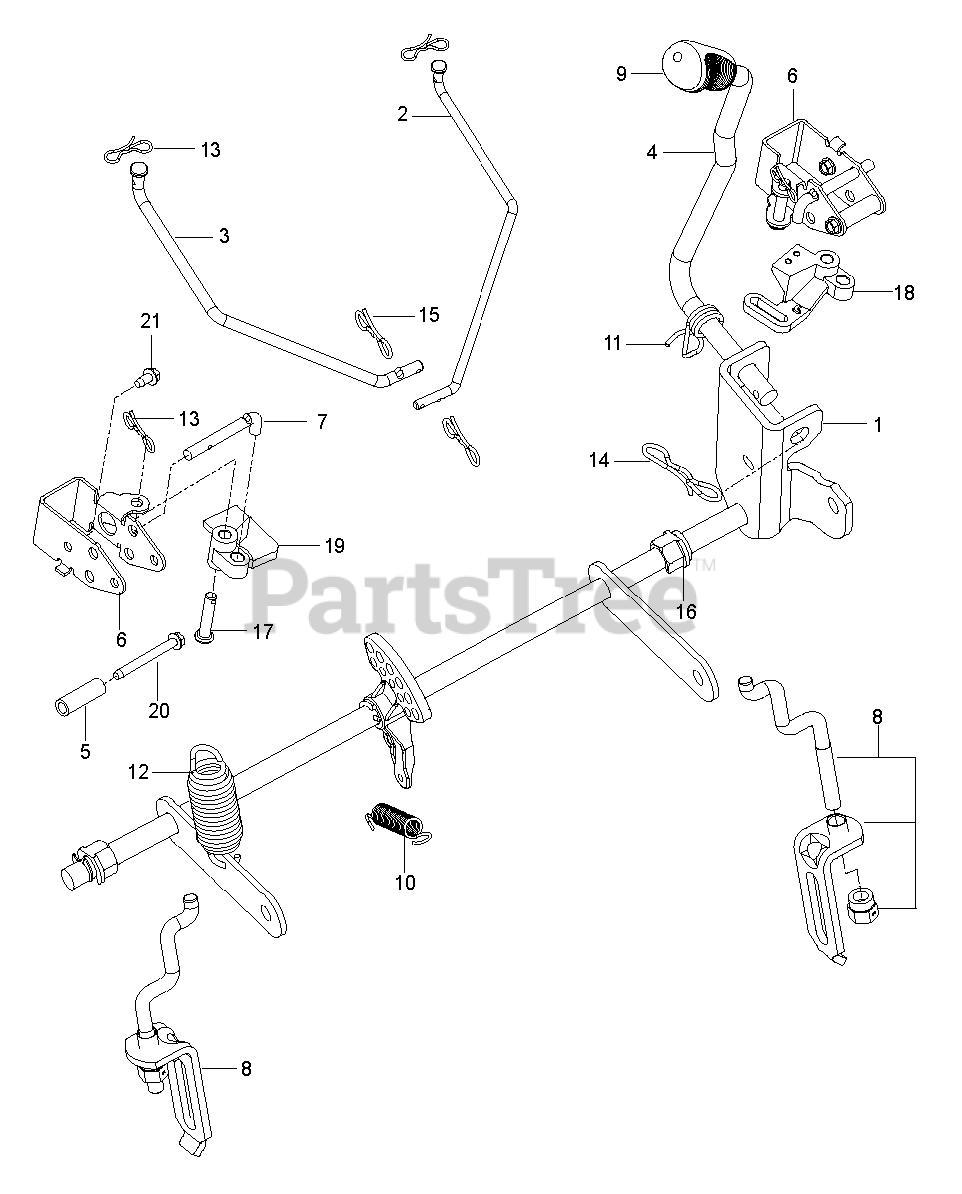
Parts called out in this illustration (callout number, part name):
1	SHAFT.ASM.RZ.DECK.LIFT.SRV
2	LINK.BRAKE.PARK.UPPER.LH
3	LINK.BRAKE.PARK.UPPER.RH
4	LIFT.LEVER.ASM.RZ.SERVICE
5	SPACER.334.ID.5.OD.1.5.L
6	BRACKET.BELLCRANK.PBRAKE X431
7	ROD.PUSH.BRAKE
8	LINK.ASM.RZ.LIFT.SERVICE
9	GRIP.HANDLE.LIFT.PVC.428
10	RETURN.BRAKE.PARK.AUTO
11	SPRING.TORSION.LIFT.HANDLE
12	SPRING
13	PIN COTTER;LOCKING;BOWTIE;1IN
14	SPRING.TORSION.LIFT.HANDLE
15	PIN.COTTER.5/16.BOW TI
16	PLASTIC NUT
17	PIN.5.16X1.5
18	BELLCRANK.LH
19	BELLCRANK.RH
20	SCREW THD;ROLL;1/4-20 X 2.25
21	SCREW.1/4-20X5/8
